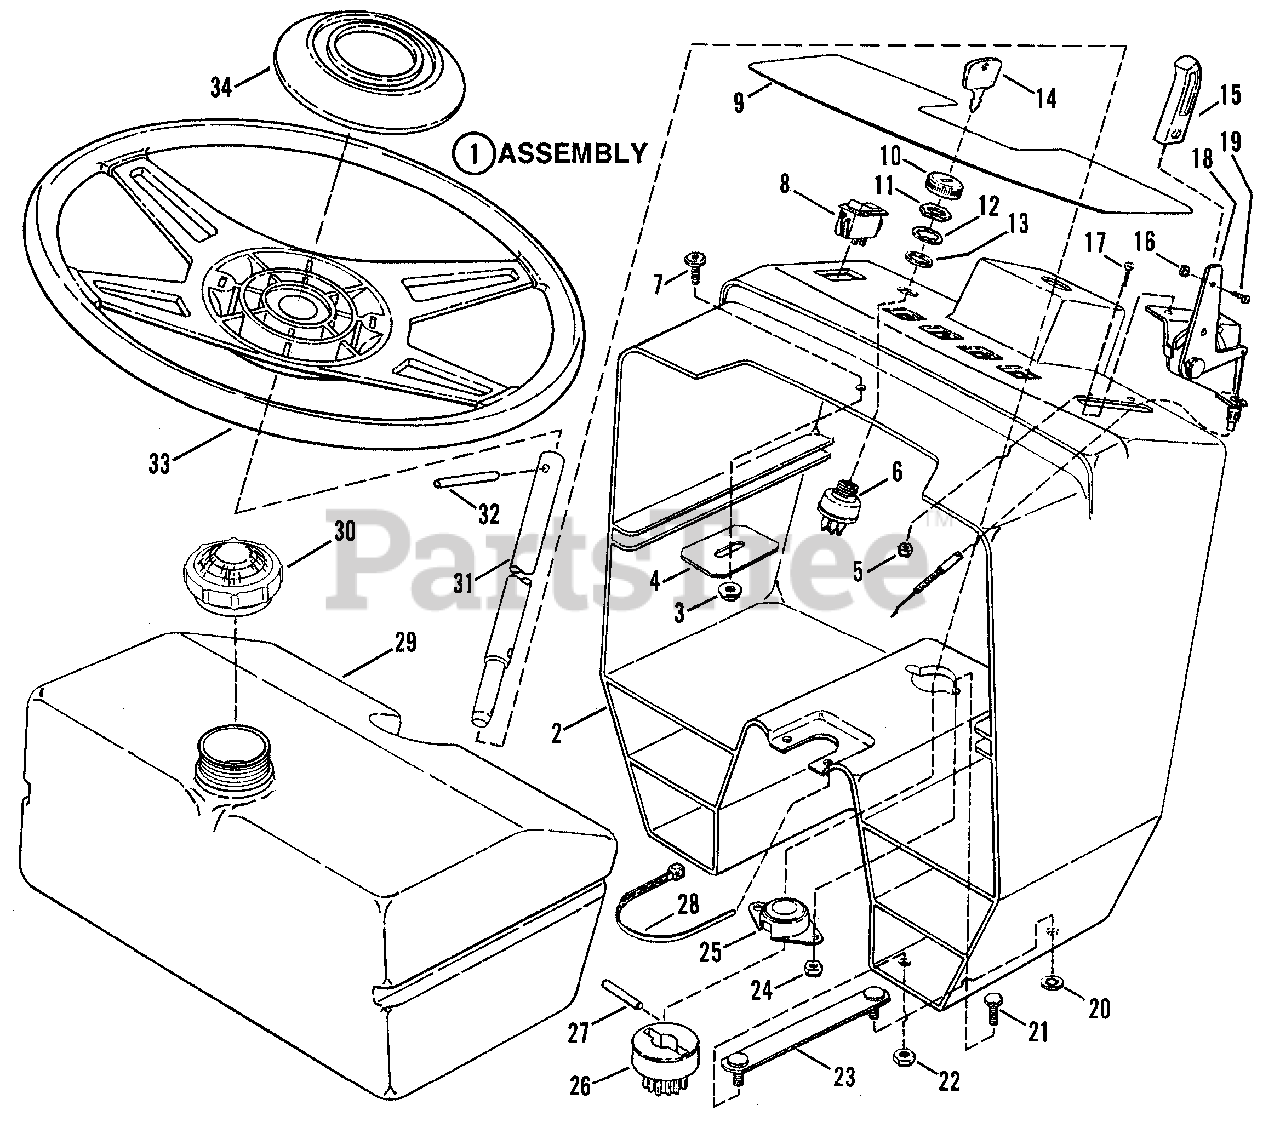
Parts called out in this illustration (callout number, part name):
1	ASSEMBLY, Console
2	CONSOLE
3	NUT, 5/16-18 Hex Flange Lock
4	BRACKET, Hood Latch Catch
5	NUT, #10-24 Hex Nyloc
6	KEYSWITCH
7	SCREW, 5/16-18 x 5/8" Torx, Truss Head
8	SWITCH, Headlights
9	DECAL, Console
10	BEZEL
11	NUT, 5/8-32 Hex
12	WASHER, 5/8 Internal Tooth Lock
13	SPACER
14	KEY (With Cover)
15	HANDLE, Throttle Control
16	NUT, #8-32 Hex
17	SCREW, #10-24 x 5/8" Mach.
18	CONTROL, Throttle 44.6" Long
19	SCREW, #8-32 x 3/8" Cross Recessed, Fillester Head
20	RETAINER
21	SCREW, 1/4-20 x 3/4" H.H.C.
22	NUT, 5/16-18 Hex Center Lock
23	ASSEMBLY, Strap-Clinch Stud
24	NUT, 1/4-20 Hex Nyloc
25	ASSEMBLY, Flange Bearing
26	GEAR, Pinion, Steering Shaft
27	PIN, Dowel, 1/4 x 1 1/4"
28	TIE, Wire
29	ASSM'Y., Fuel Tank
30	CAP, Fuel Tank
31	SHAFT, Steering
32	ROLL-PIN
33	STEERING WHEEL
34	CAP, Steering Wheel
